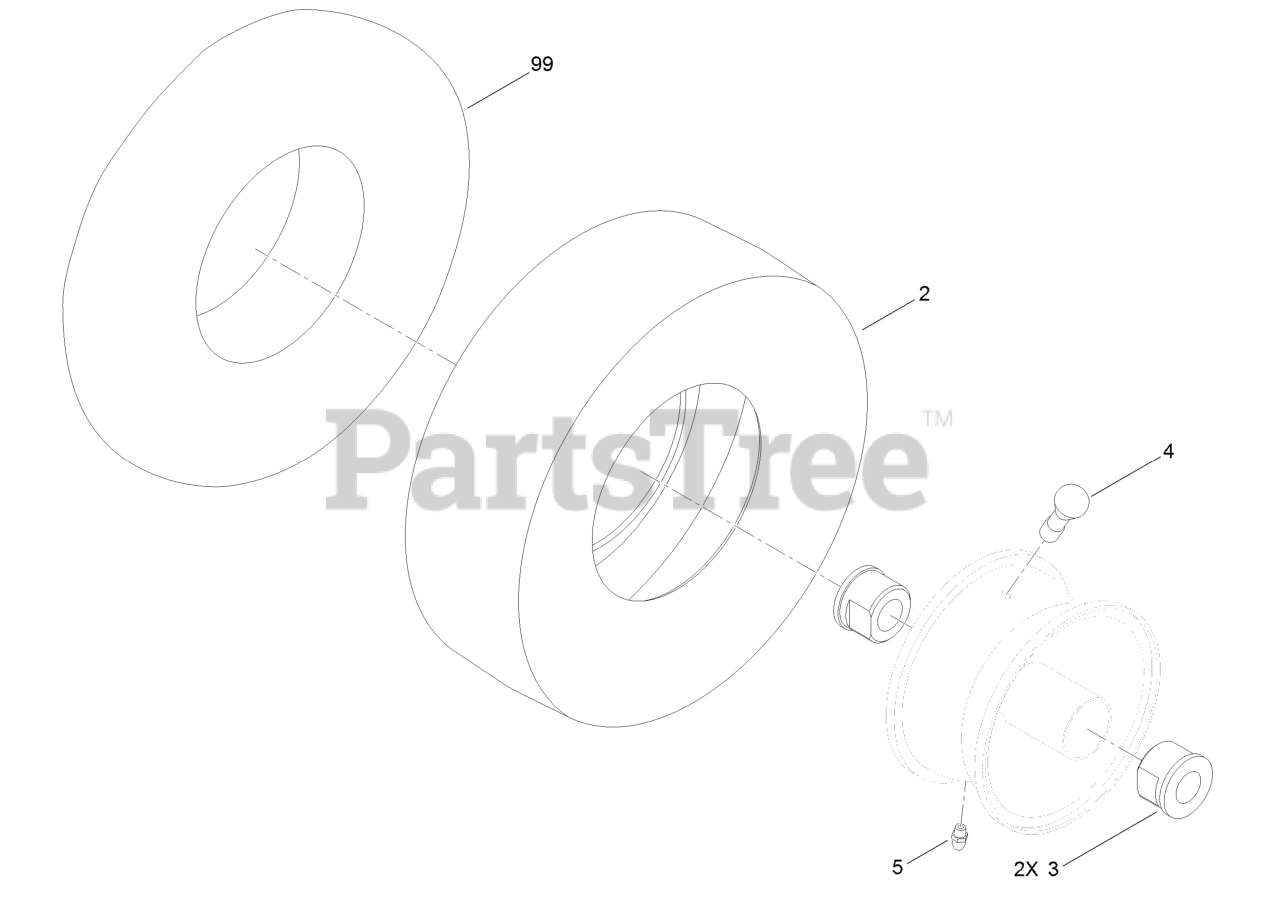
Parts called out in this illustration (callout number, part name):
3	Bushing-Flange
4	Stem-Valve
5	Fitting-Grease
99	Tube-Inner
